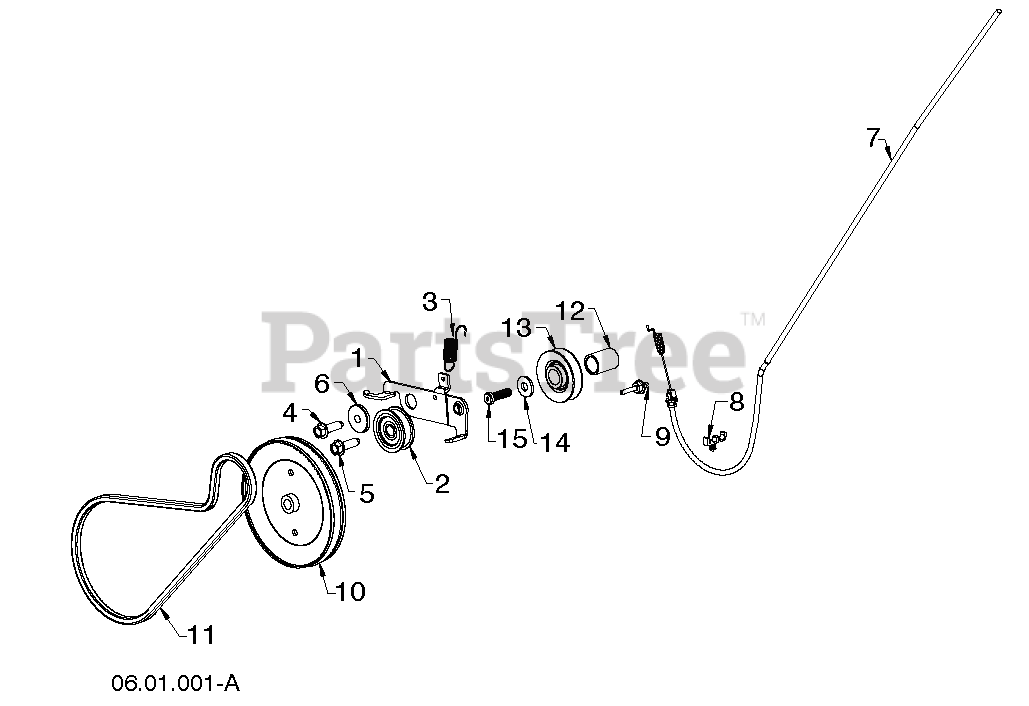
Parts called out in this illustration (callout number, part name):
1	ARM.IDLER.PNT
2	IDLER PULLEY
3	SPRING.EIDLER.PULLEY.RETURN
4	SCREW.3/8-16
5	SCREW.3/8-16
6	SPACER.RETAINER
7	CABLE.CLUTCH.SSST.SHORT
8	PUSH CLIP
9	KEEPER.ENGINE.BELT
10	PULLEY.DRIVEN
11	BELT.4L.1/2X35
12	SPACER.ENGINE.CRANK
13	PULLEY.ENG.TRACTION
14	WASHER,HARDEN
15	BOLT, SCKT HD 3/8-24 X 1 .25
